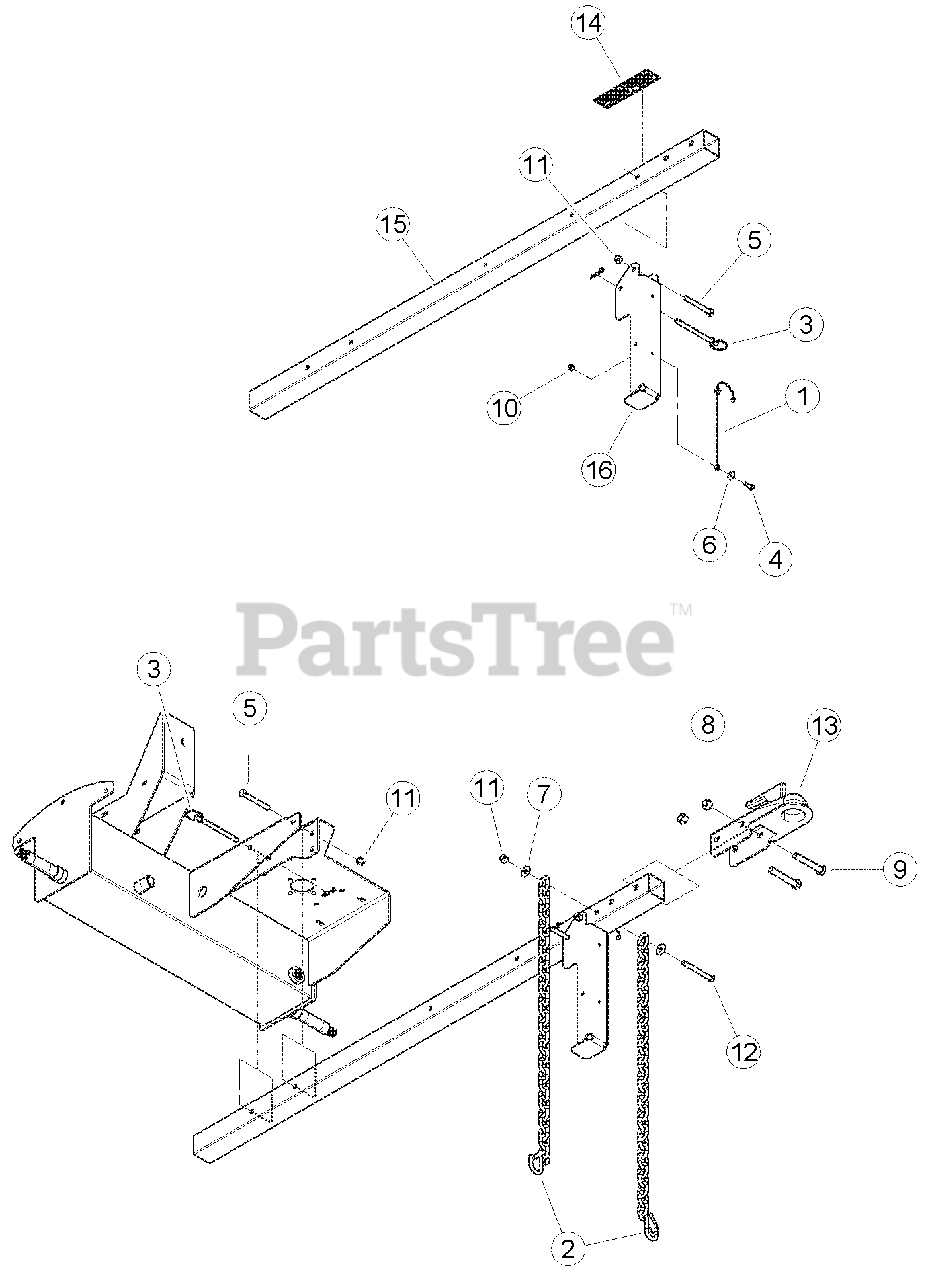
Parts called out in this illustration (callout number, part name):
1	LANYARD, NYLON
2	CHAIN, SAFETY 5000 LB W/LATCH
3	PIN, 3/8 HITCH
4	BOLT, 1/4 X 3/4 HEX HD GR5 ZP
5	BOLT, 3/8 X 3 HEX HD GR5 ZP
6	WASHER, 1/4 FLAT ZP
7	WASHER, 3/8 FLAT ZP
8	NUT, 1/2 CENTERLOCK GRB ZP
9	BOLT, 1/2 X 3 HEX HD GR5 ZP
10	NUT, 1/4 NE NYLOCK ZP
11	NUT, 3/8 NE NYLOCK ZP
12	BOLT, 3/8 X 3-1/4 HEX HD GR5 ZP
13	TRAILER HITCH COUPLER
14	DECAL, WARNING TOWING SPEED
15	TUBING, HITCH POLE
16	STAND, JACK
